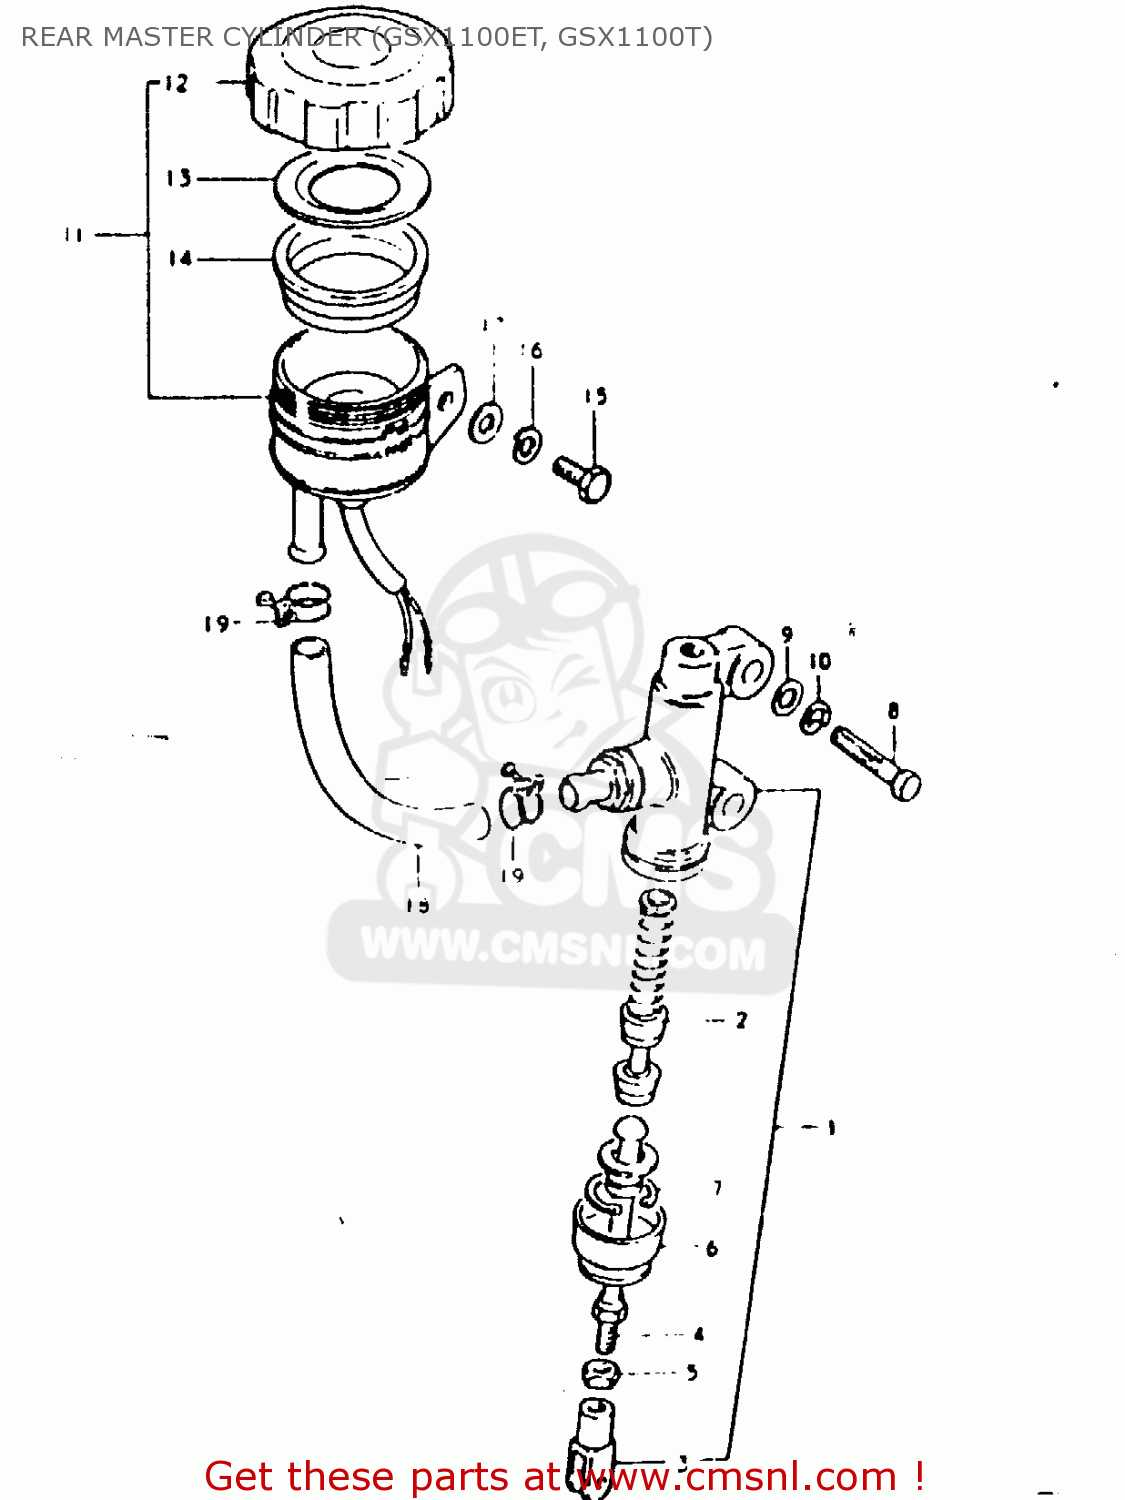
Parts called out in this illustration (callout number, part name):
1	CYLINDER ASSEMBLY,REAR MASTER
2	PISTON/CUP SET
3	YOKE
4	ROD,PUSH
5	NUT
6	BOOT
7	CIRCLIP
8	BOLT (8X30)
9	WASHER
10	LOCK WASHER
11	RESERVOIR TANK ASSY
12	CAP
13	PLATE,DIAPHRAGM
14	DIAPHRAGM
15	BOLT
16	LOCK WASHER
17	WASHER
18	HOSE,RESERVOIR TANK
19	CLAMP
